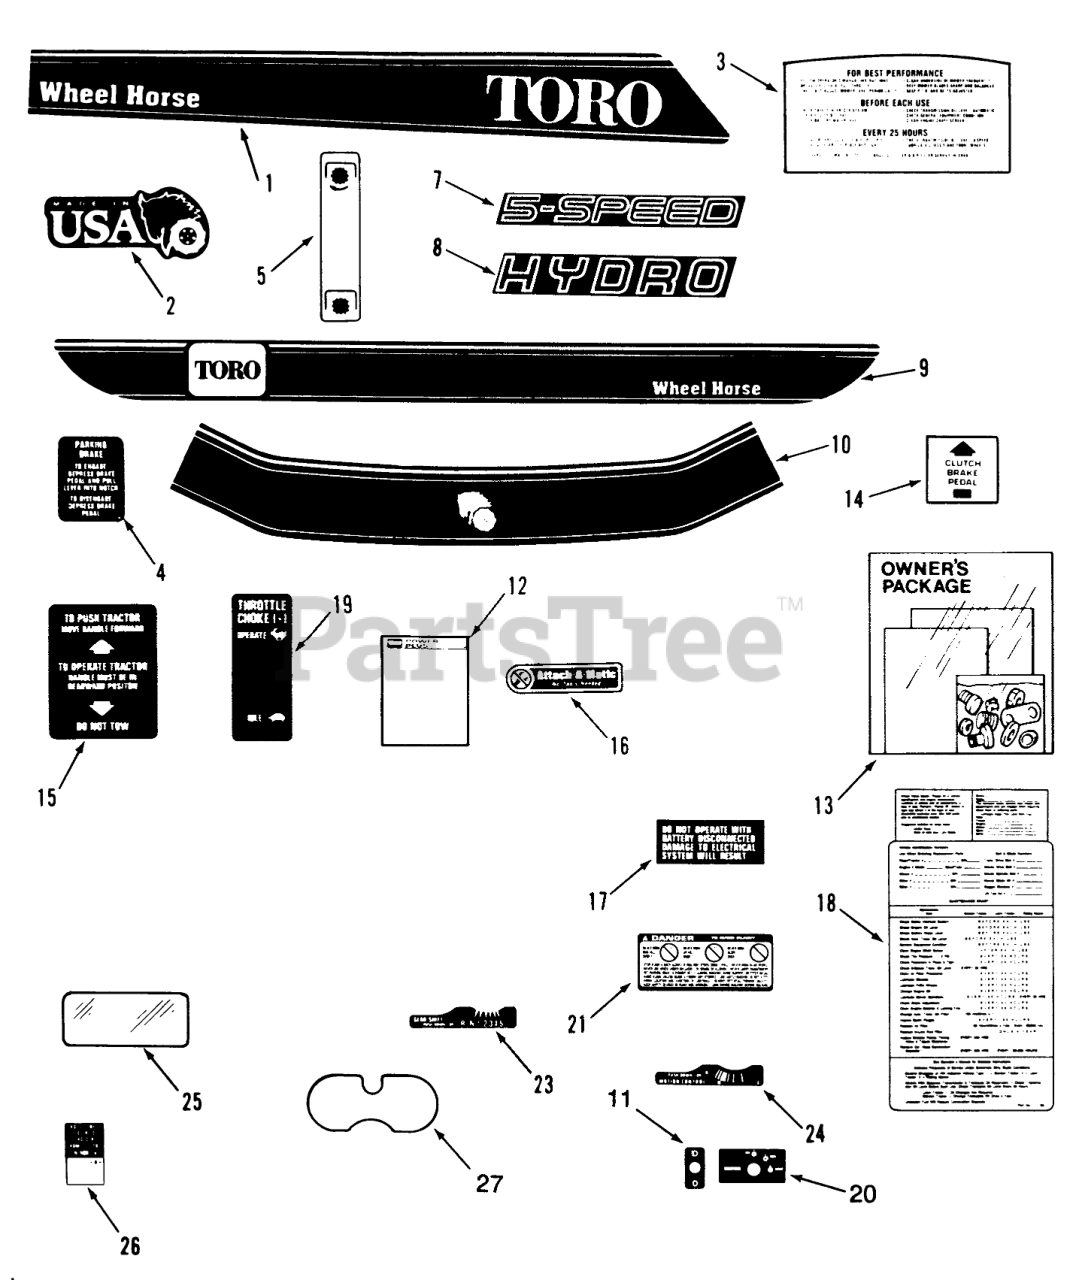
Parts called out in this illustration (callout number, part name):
1	DECAL-HOOD 212-5 R H
2	Decal-Made In USA
3	Decal-Hood Rear
4	DECAL PARKING BRAKE
5	DECAL-PTO
7	DECAL-MODEL 5-SPEED
8	DECAL-MODEL HYDRO
9	DECAL-FENDER
10	DECAL-FRONT HOOD
11	DECAL-LIGHTS
13	Loose Parts Package (212-5)
14	DECAL CLUTCH & BRAKE
15	DECAL-PUSH
16	Decal-Attach-A-Matic
17	DECAL ELECT SYSTEM
18	MAINTENANCE-DECAL
19	Decal-Throttle
20	DECAL-IGNITION
21	DECAL-DANGER
23	DECAL-SHIFT 5-SPEED
24	DECAL-MOTION CONTROL
25	DECAL-OVERLAY
26	DECAL-PTO BELT ADJ
27	DECAL-SEAT LIFTER
